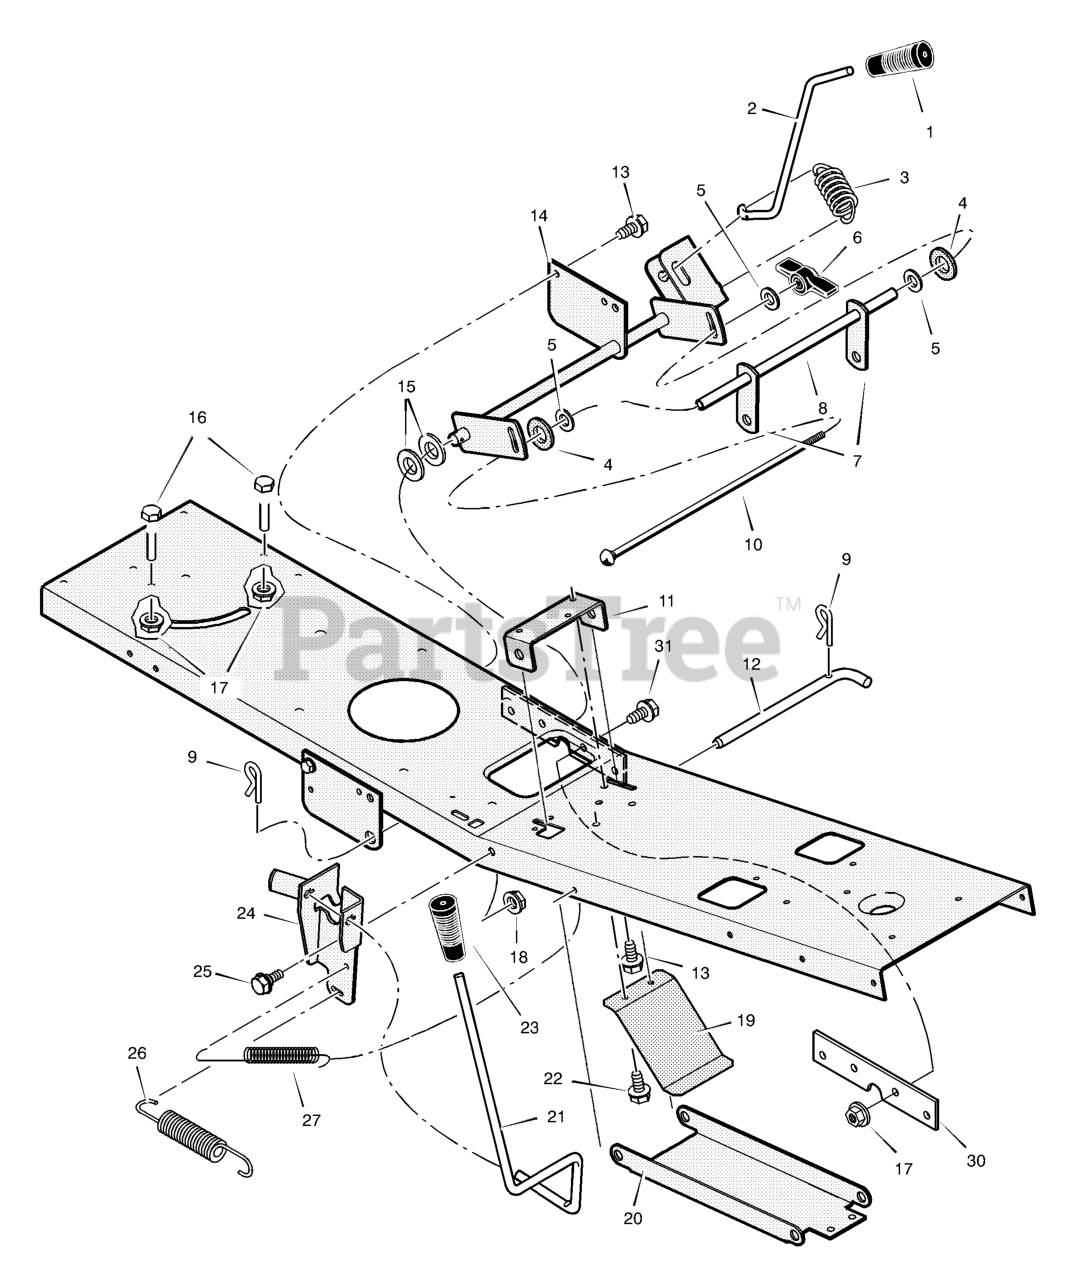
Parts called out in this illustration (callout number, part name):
1	Grip, Lift Lever
2	Lever, Lift
3	Spring, Extension
4	Pad, Friction
6	Wingnut
7	Link, Lift
8	Tube, Spacer
9	Pin, Hair
10	Bolt, Carriage
11	Bracket, Front Hanger Pivot
12	Pin, Front Hanger
14	Arm Assembly, Lifter
15	Washer
16	Screw, Guide
17	Nut, Flange
18	Nut, Flange
19	Spring, Leaf
20	Hanger, Front
21	Lever, PTO
23	Grip, PTO
24	Bracket, PTO
25	Bolt, Shoulder
26	Spring, Extension
27	Spring, Extension
30	Plate, Reinforcement
